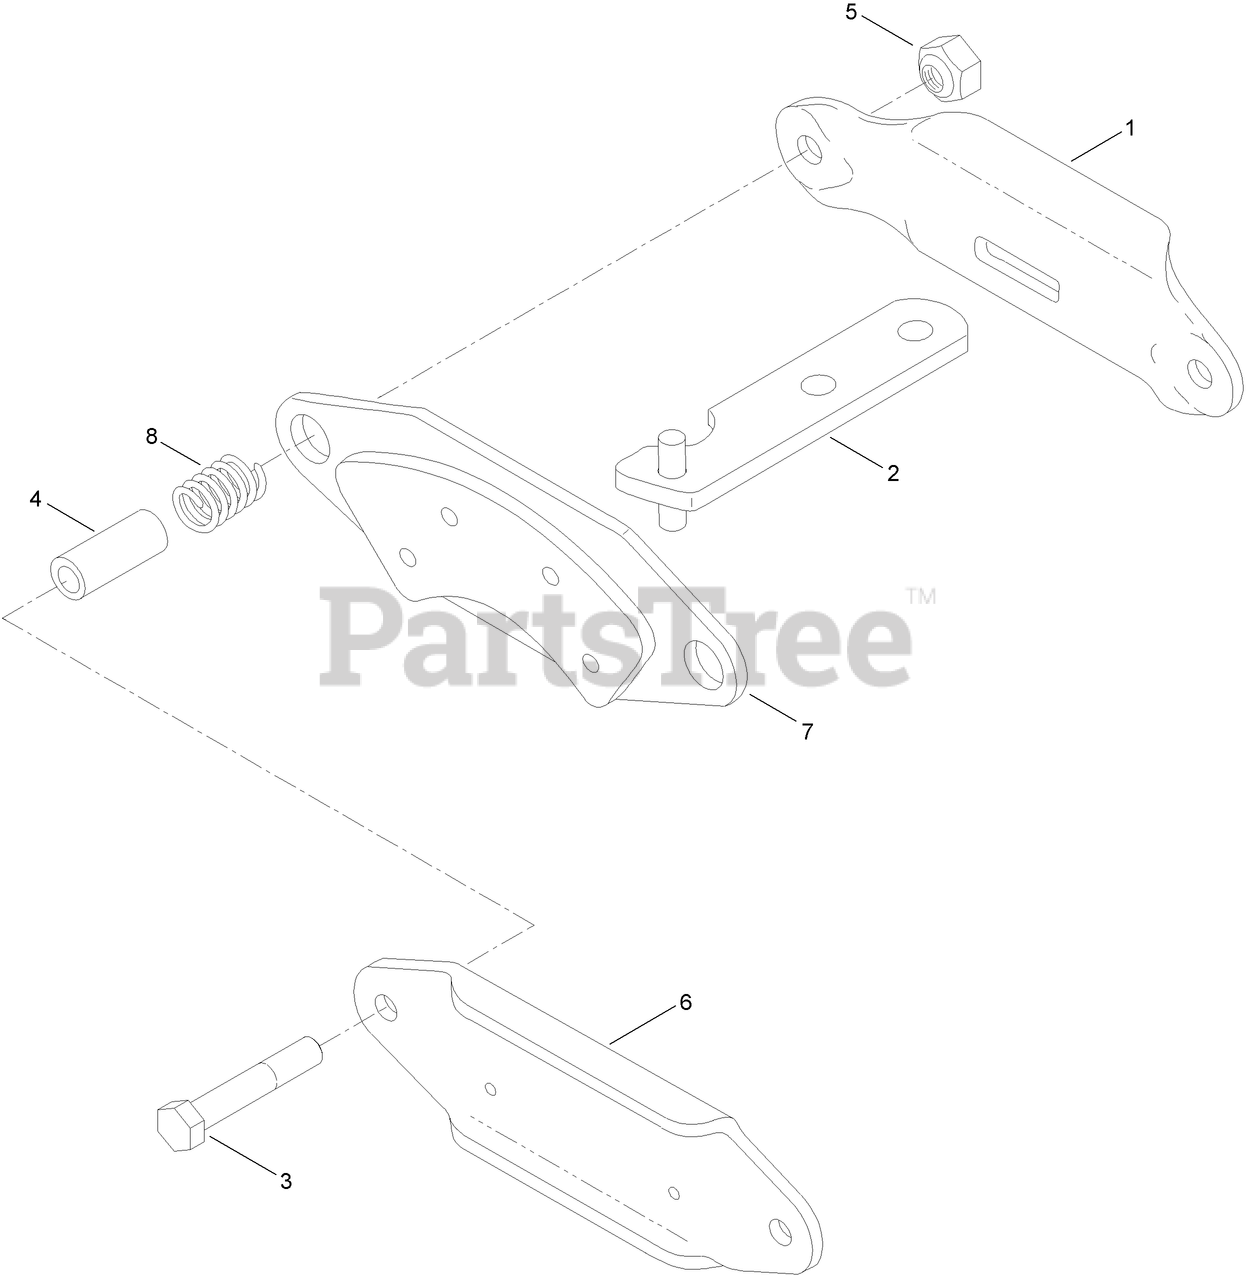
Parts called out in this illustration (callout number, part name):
1	BRACKET
3	SCREW-CAP
4	SPACER-TUBE
6	OUTSIDE HOLDER AND PAD ASM
7	INSIDE HOLDER AND PAD ASM
